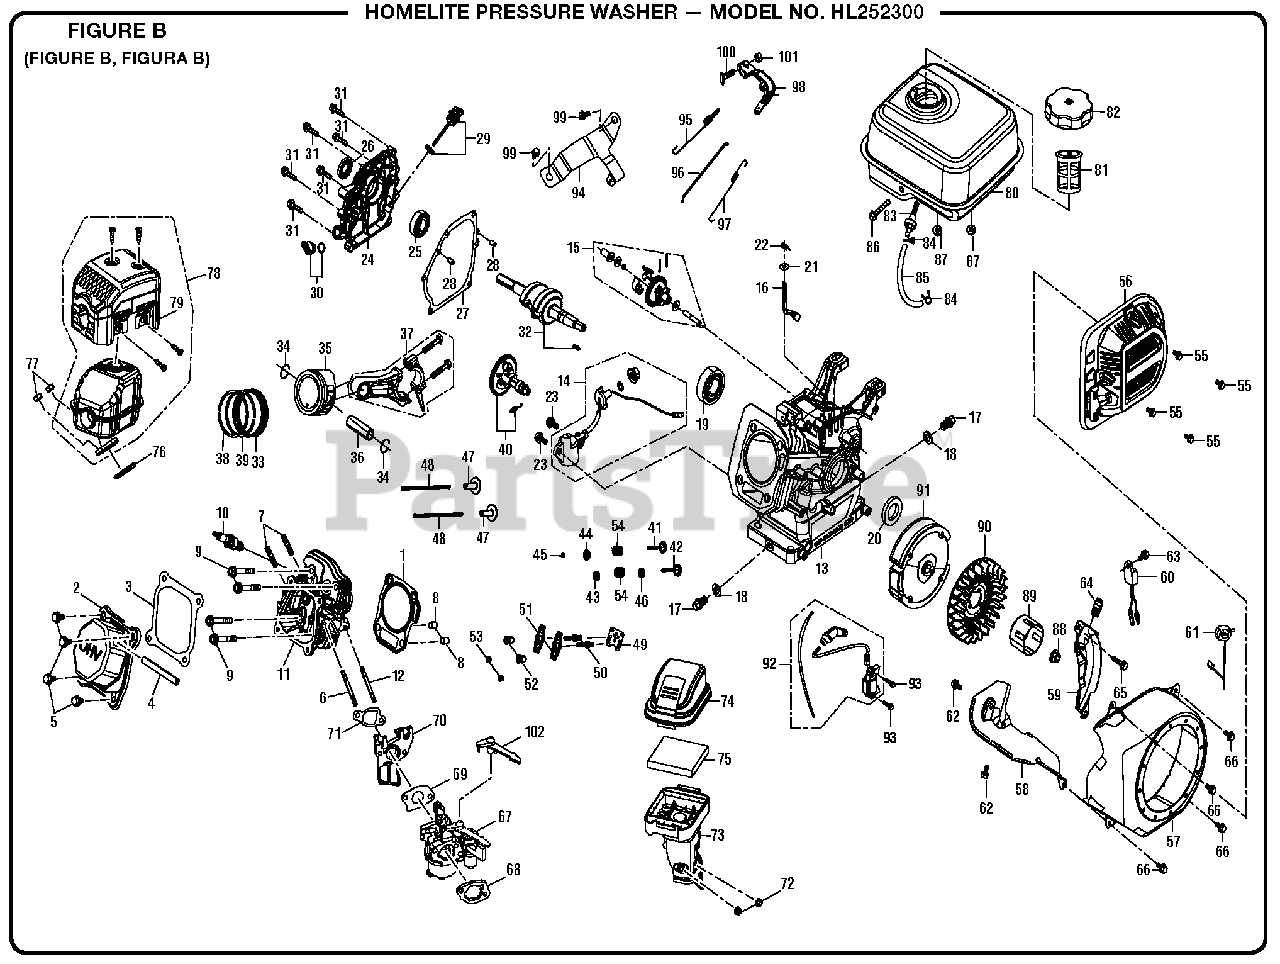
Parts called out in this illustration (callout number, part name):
1	Cylinder Head Gasket
2	Cylinder Head Cover Assembly
3	Gasket Cylinder Head Cover
4	Breather Tube
9	Cylinder Head Bolt
11	Cylinder Head Assembly
13	Crankcase Assembly
14	Engine Oil Sensor
15	Governor Gear Assembly
16	Governor Arm
17	Drain Plug Bolt
21	Governor Gear Washer
24	Crankcase Cover Assembly
27	Crankcase Gasket
29	Oil Dipstick Assembly
30	Engine Oil Plug Assembly
32	Crankshaft Assembly
33	Oil Ring Set
34	Piston Pin Clip
35	Piston Assembly
37	Connecting Rod
39	Second Ring
40	Camshaft Assembly
41	Exhaust Valve
42	Intake Valve
43	Valve Spring Seat
44	Exhaust Valve Retainer
45	Valve Rotator
47	Valve Tappet
48	Valve Lifter
49	Lifter Stopper Plate Assembly
50	Valve Adjusting Bolt
51	Valve Rocker
52	Valve Adjusting Nut
53	Valve Lock Nut
54	Valve Spring
55	Bolt
56	Recoil Starter Assembly
58	Cylinder Body Shroud
59	Lower Shield
60	Oil Protector
61	Stop Engine Switch Assembly
67	Carburetor Assembly
68	Air Cleaner Gasket
69	Carburetor Gasket
70	Carburetor Insulator Plate
71	Carburetor Insulator Gasket
73	Air Cleaner Assembly
74	Air Cleaner Case Cover
75	Air Cleaner Element
76	Exhaust Outlet Gasket
78	Muffler Assembly
79	Muffler Outer Cover
81	Fuel Strainer
82	Fuel Tank Cover
83	Fuel Tank Oil Outlet Assembly
89	Starter Pulley
91	Flywheel Assembly
92	Ignition Coil
94	Throttle Control Assembly
95	Governor Spring
96	Governor Rod
97	Throttle Valve Return Spring
98	Governor Support Assembly
100	Governor Support Bolt
102	Choke Lever
